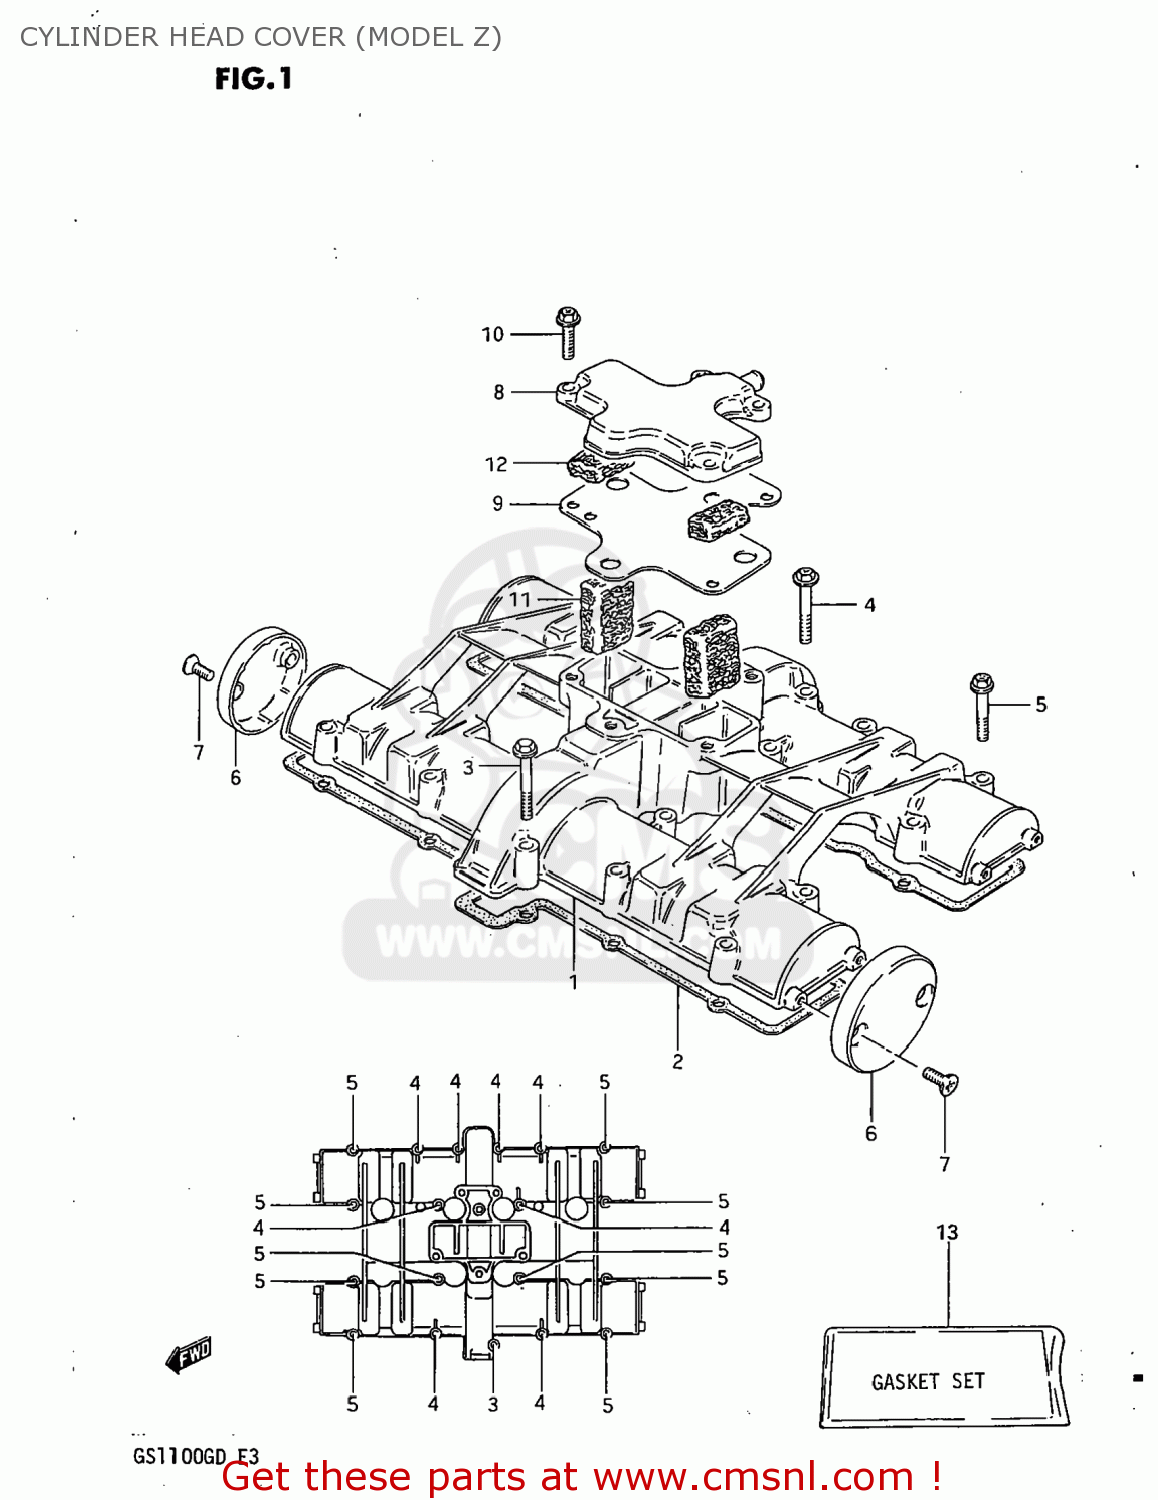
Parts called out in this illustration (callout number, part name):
1	COVER,CYLINDER HEAD
2	GASKET,CYLINDER HEAD COVER (MCA)
3	BOLT,UNDER
4	BOLT
5	BOLT 6X35
6	CAP,CYLINDER HEAD COVER
7	SCREW(5X12)
8	COVER,BREATHER
9	GASKET (MCA)
10	BOLT
11	COVER,BREATHER
12	SEPARATOR,OIL BREATHER
13	GASKET SET (MCA)
